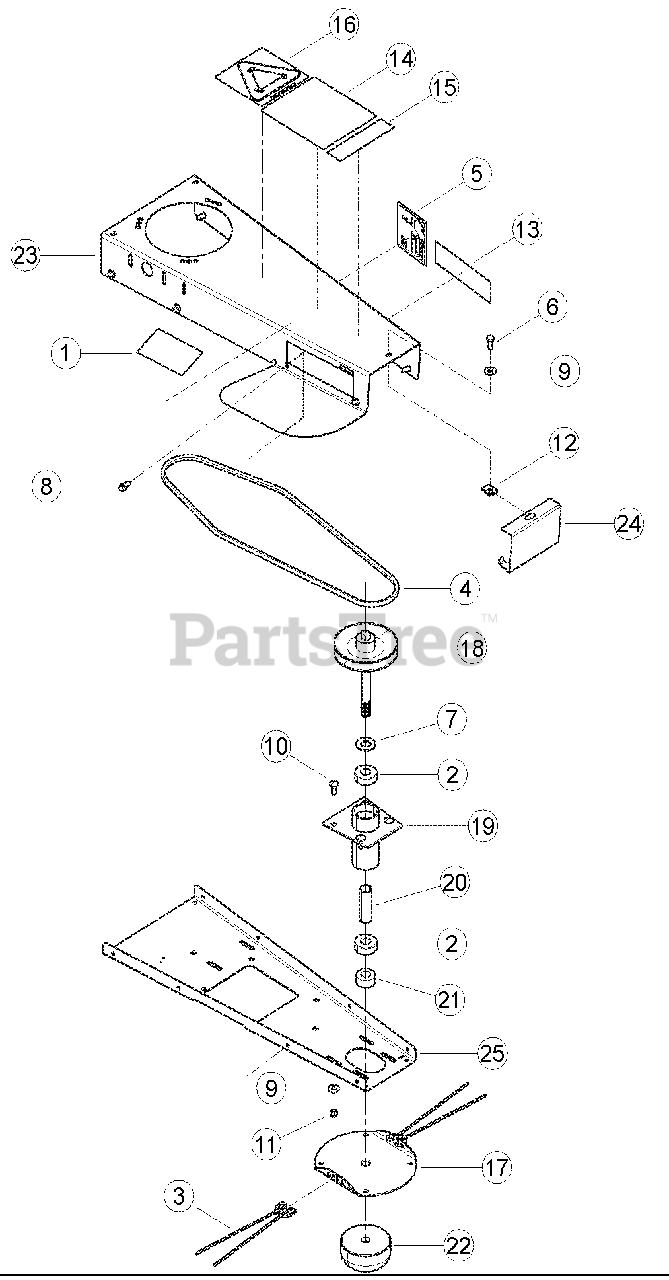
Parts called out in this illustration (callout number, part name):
1	DECAL, GRINDER DANGER
2	BEARING, 3/4 BALL
3	STRING, .155 X 20-1/2
4	BELT, 3L X 52
5	DECAL, 98 DB (WT160S)
5	DECAL, 101 DB (WT190S)
6	BOLT, 5/16 3/4 HEX HD GR5 ZP
7	WASHER, 3/4 SAE FLAT ZP
8	SCREW, 11/32 X 7/8 HWH AB THREAD ZP
9	WASHER, 5/16 FLAT ZP
10	BOLT, 5/16 X 7/8 CRG GR5 NC ZP
11	NUT, 5/16 NE NYLOCK ZP
12	NUT 5/16-18 TINNERMAN U-TYPE
13	DECAL, ECHO BEARCAT 6.82 X 1.90
14	DECAL, MANUAL/SAFETY INFO
15	DECAL, MODEL WT160S
15	DECAL, MODEL WT190S
16	DECAL, RECLAIM IT
17	DISK, TRIMMER HEAD
18	WELDMENT, TRIMMER PULLEY
19	WELDMENT, SPINDLE HUB
20	SPACER, TRIMMER SPINDLE
21	SPACER, TRIMMER HEAD
22	WELDMENT, TRIMMER HEAD USE 72704-12
23	BODY, TRIMMER
24	COVER, FRONT TRIMMER
25	BOTTOM, TRIMMER FRAME
